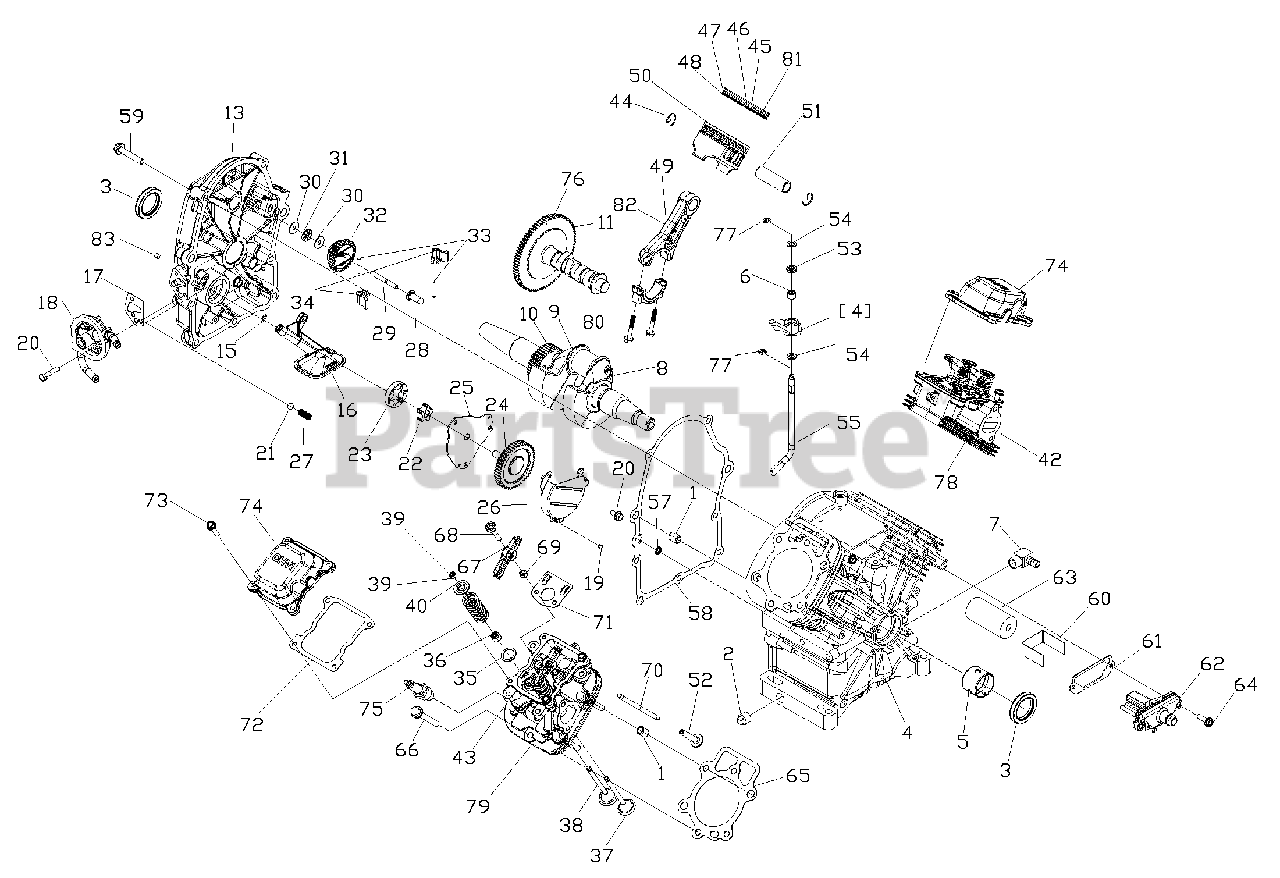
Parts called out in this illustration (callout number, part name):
1	SLEEVE DOWEL PIN 12 DIA
2	PLUG STD PIPE 3/8 S TEEL SQ HEAD
3	SEAL CRANKSHAFT OIL-35 DIA
4	SUBASSEMBLY CRANKCASE GTH530
5	BEARING 35MM ID GT530
6	BEARING NEEDLE 8X12X8 OPEN
7	ELBOW 90 DEG 3/8 NPT W/VS
8	PLUG EXPANSION
9	CRANKSHAFT GTH530
10	GEAR CRANKSHAFT
11	GEAR CAMSHAFT GT530
13	COVER GEAR MACHINED
15	O-RING 3/8 X 1/2
16	PICK UP SCREEN OIL
17	GASKET OIL FILTER ADAPTOR
18	ASSEMBLY OIL COOLER ADAPTOR W/PRES RELIEF
19	RIVET POP
20	SCREW SHC M6-1 X 30
21	BALL RELIEF
22	GEROTOR INNER GT530
23	GEROTOR OUTER GT530
24	GEAR GEROTOR GT530
25	COVER GEROTOR
26	COVER GEAR SHIELD
27	SPRING OIL PRESSURE RELIEF
28	SPOOL GOVERNOR
29	SHAFT GOVERNOR
30	BEARING ROLLER GOV TOP PLATE
31	ROLLER BEARING
32	GEAR GOVERNOR
33	FLYWEIGHT GOVERNOR
34	PIN GOVERNOR FLYWEIGHT RETAINER
35	WASHER VALVE SPRING WEAR
36	SEAL VALVE STEM
37	VALVE EXHAUST
38	VALVE INTAKE
39	KEEPER VALVE SPRING
40	VALVE RETAINER
41	SPRING VALVE SF
42	ASSY CLY HEAD 1 GUIDES AND SEATS
43	ASSY CYL HEAD 2 GUIDES AND SEATS
44	RING RETAINING
45	RING PISTON TOP N 75
46	RING PISTON 2ND N 75
47	RING PISTON OIL RAIL N 75
48	RING PISTON OIL SPACER N 75
49	ASSY CONROD GT530
50	PISTON COATED N 75
51	PIN PISTON
52	TAPPET 7.5 DIA
53	SEAL GOVERNOR ARM GT530
54	SHIM GOVERNOR ARM 8X14X1
55	ARM GOVERNOR
57	SEAL OIL PASSAGE
58	GASKET CRANKCASE
59	SCREW HHFC M8-1.25 X 45
60	SEPARATOR OIL
61	GASKET BREATHER ASSY
62	ASSY BREATHER PLASTIC
63	SEPARATOR OIL BREATHER
64	SCREW HHFC M6-1.0 X 20
65	GASKET CYLINDER HEAD
66	SCREW HHC M8-1.25 X 56
67	ARM ROCKER GH220
68	STUD ROCKER ARM PIVOT
69	NUT JAM M6-0.75 FINE THREAD
70	PUSHROD ALUMINUM
71	PLATE PUSH ROD GUIDE
72	GASKET VALVE COVER
73	SCREW HHFC M6-1 X 8
74	COVER ROCKER
75	SPARK PLUG
76	ASSY CAM & GEAR
77	RING RETAINING E-STYLE
78	KIT HEAD ASSY CYL 1
79	KIT HEAD ASSY CYL 2
80	KIT CSHAFT W/PLUG
81	RING SET
82	ASSY PISTON AND CONNECTING ROD
83	SCREW SHC 5/16-24 X 3/8
